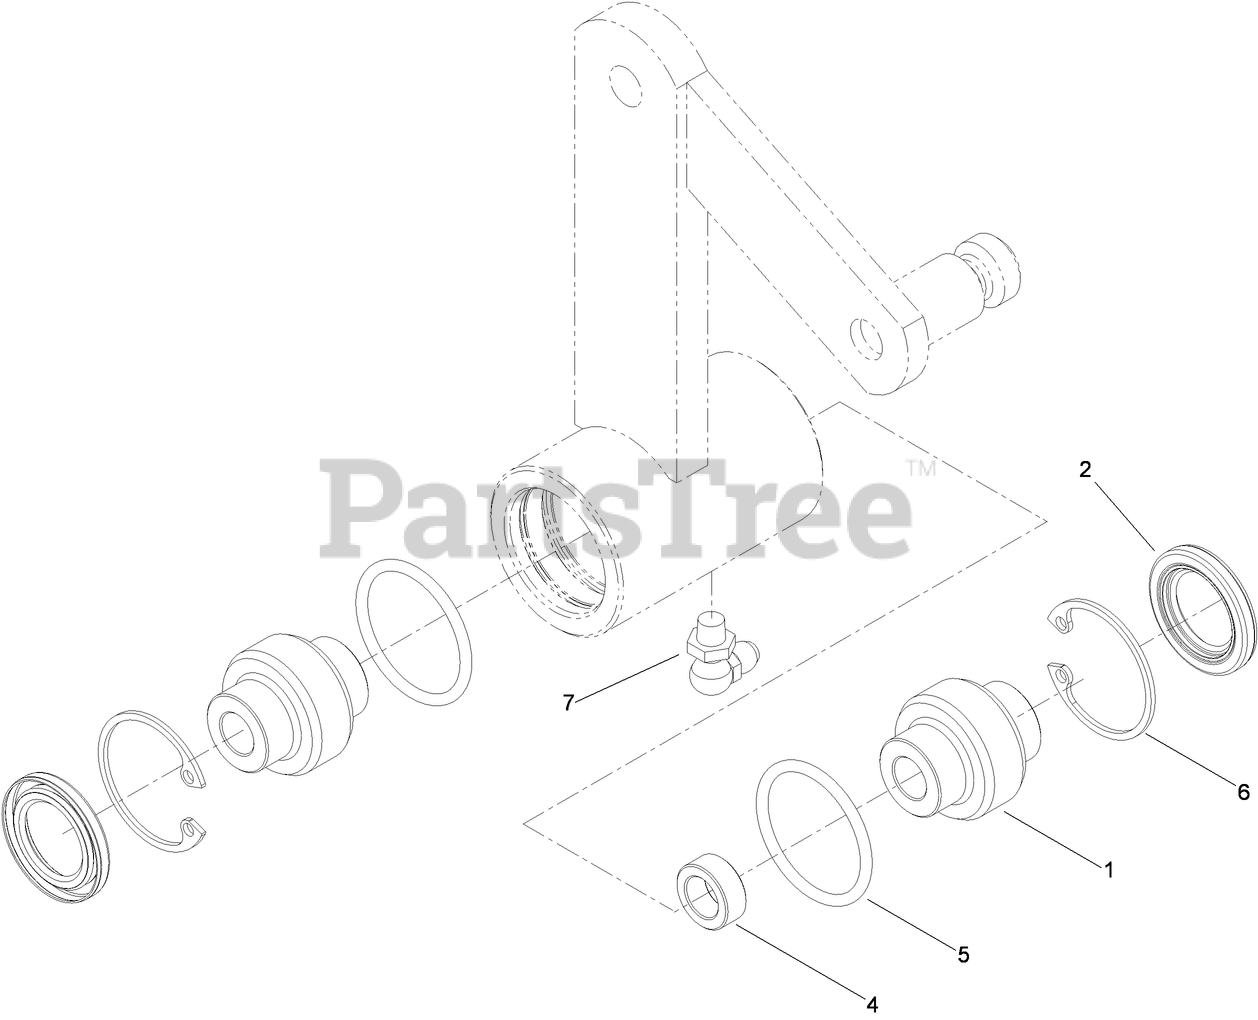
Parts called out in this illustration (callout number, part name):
1	BEARING-SPHERICAL
2	SEAL-LIP, SINGLE
4	SPACER
5	O-RING
6	RING-SNAP
7	FITTING-GREASE, 90 DEG
